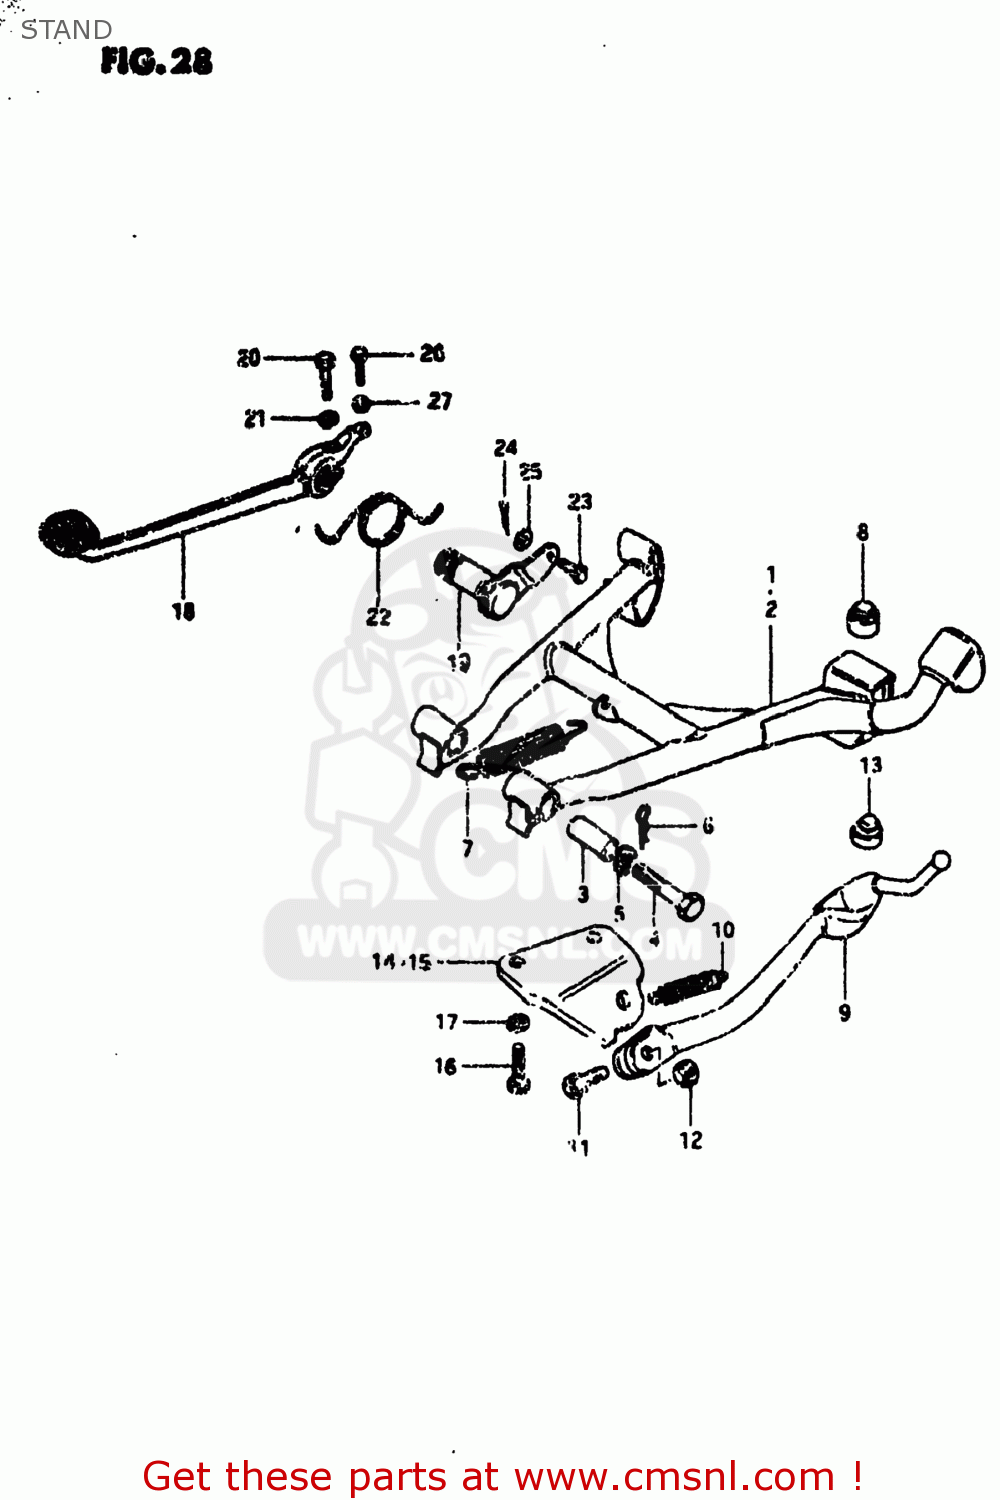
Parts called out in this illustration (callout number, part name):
1	STAND,CENTER
2	STAND,CENTER
3	SPACER(10X16X38.8)
4	BOLT
5	LOCK WASHER
6	CLIP
7	SPRING
8	CUSHION
9	STAND,PROP
10	SPRING
11	BOLT(10X30)
12	NUT
13	CUSHION
14	BRACKET,SIDE STAND
15	BRACKET,SIDE STAND
16	BOLT
17	LOCK WASHER
18	PEDAL,BRAKE
19	ARM,BRAKE PEDAL
20	BOLT
21	LOCK WASHER
22	SPRING
23	PIN
24	PIN
25	WASHER
26	BOLT
27	NUT
